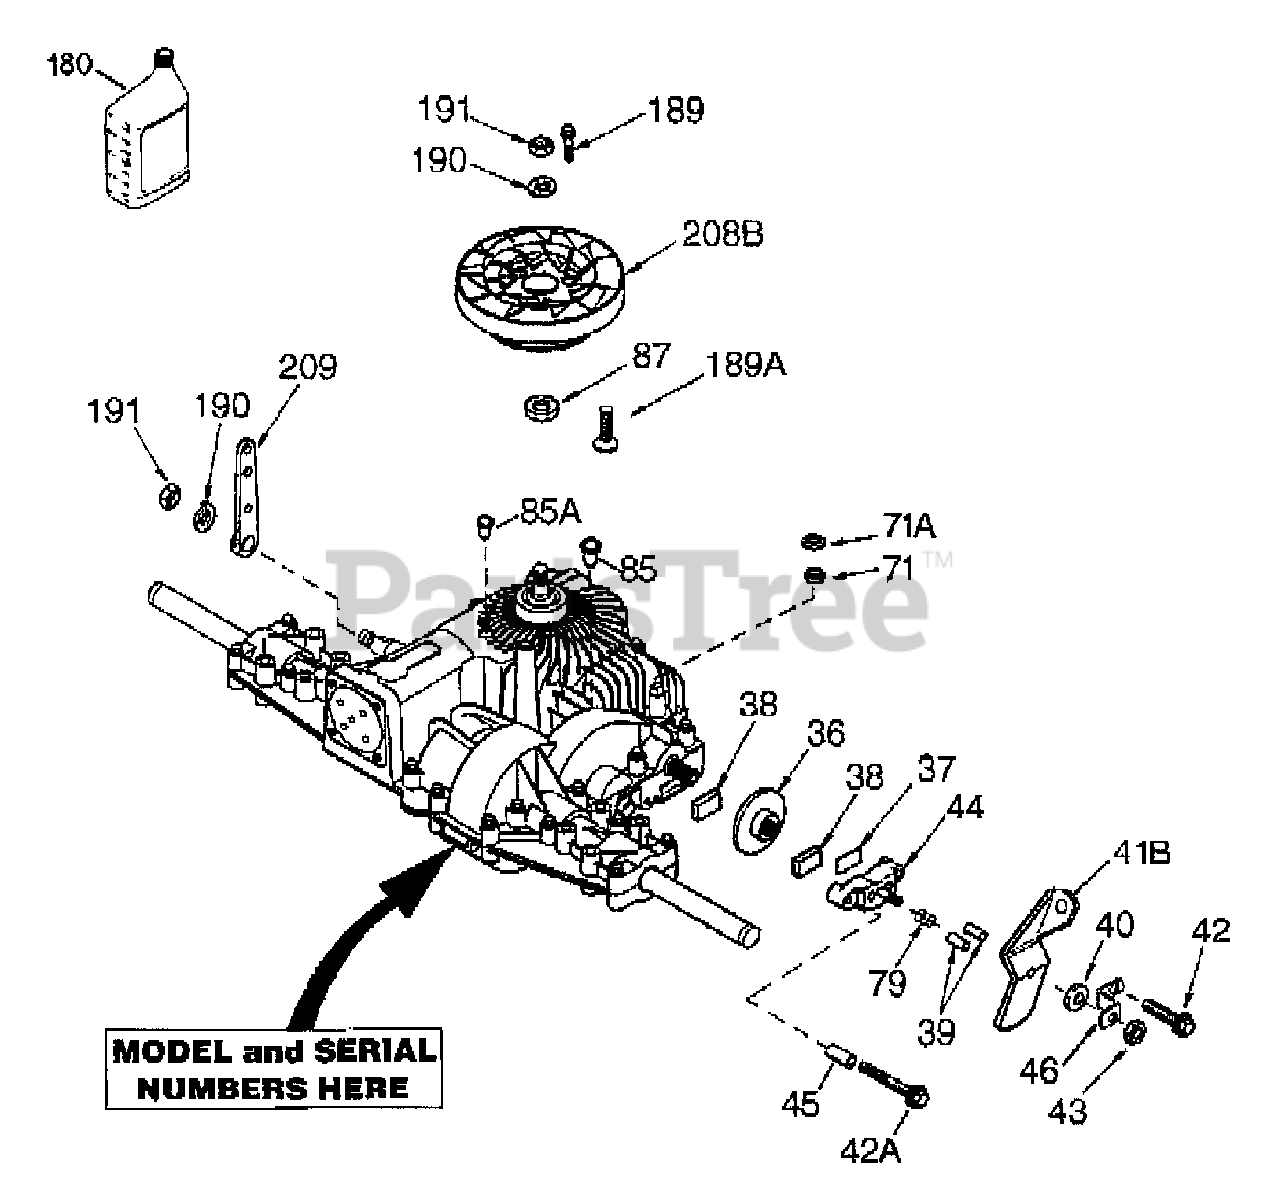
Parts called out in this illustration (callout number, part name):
36	Brake Disc
37	Brake Pad Plate
38	Brake Pad
39	Dowel Pin
40	Flat Washer
41B	Brake Lever
42	Screw, 1/4-20 x 1-1/4
42A	Screw, 1/4-20 x 2-1/4
43	Locknut, 5/16-24
44	Brake Pad Holder
46	Brake Lever Bracket
71	Square Cut Ring
71A	Pushnut, 9/16
85	Oil Fill Plug
85A	Tube Plug, 3/8
87	Oil Seal, 5/8
180	Gear Oil 80W90
189	Drive Screw #6 x 1/2
189A	Screw, 10-32 x 1/2
190	Lockwasher
191	Nut, 7/16-20
208B	Fan/Coupling
209	Control Lever
